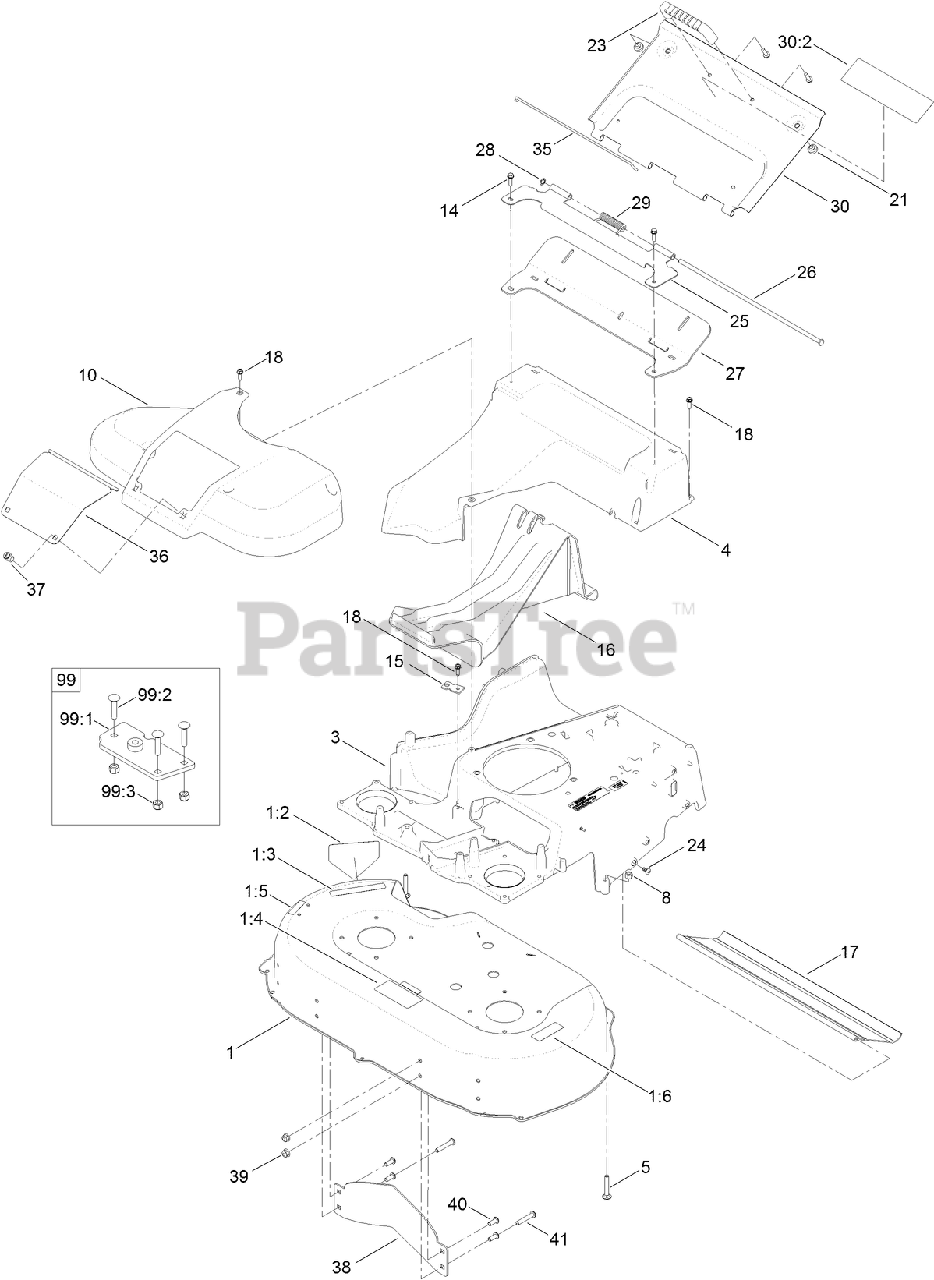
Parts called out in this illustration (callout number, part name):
1	DECK-30 INCH
1:2	DECAL-DANGER
1:3	DECAL-DANGER
1:5	DECAL-WARNING
1:6	DECAL-WARNING, BLOCK
3	FRAME
4	CHUTE
5	SCREW-CARR
8	NUT-LOCK, NI
10	COVER-BELT
14	SCREW-HWH
15	BRACKET-CABLE, TRACTION
16	PLUG-MULCH
17	SHIELD-TRAILING
18	SCREW-HWHTF
21	BUMPER
23	HANDLE-DOOR
24	SCREW-PTH
25	BRACKET-HINGE
26	PIN-HINGE
27	SEAL-DOOR
28	RING-RETAINING
29	SPRING-TORSION, COVER
30	REAR DOOR ASM
30:2	DECAL-WARNING
35	CLIP-SEAL
36	DOOR-ACCESS
37	FASTENER
38	BAFFLE-CONTROL
39	NUT-HF, NI
40	SCREW-HSBH
41	SCREW-HSBH
99	FRAME PLATE KIT
99:1	PLATE-FRAME
99:2	SCREW-CARR
99:3	NUT-LOCK, NI
